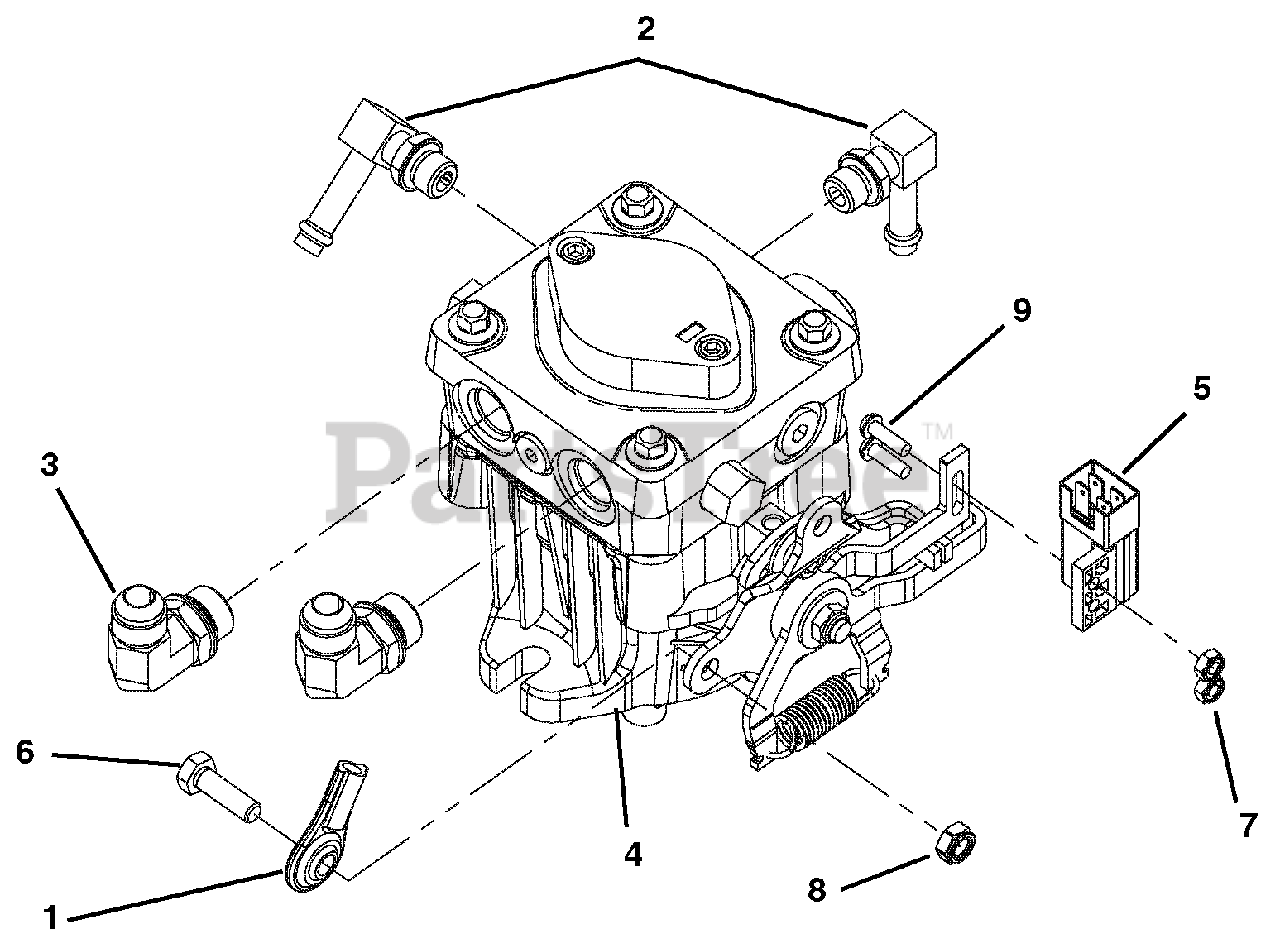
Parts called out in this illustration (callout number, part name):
1	Alignaball, 5/16 RH/Thread
2	Fitting, 90 9/16MOR x 3/8 Hose
3	Fitting
4	Pump, Hydraulic
5	Switch, Plunger Diametral Pitch -N.O. -N.C.
6	Bolt, Hex 5/16-18 x 1.00 Grade 5
7	Nut, Locking, Nylon 10-24 w/Insert
8	Nut, Locking, Nylon .312-18
9	Screw, Machine 10-24 x .62 P/HD
NS	Pump Seal Kit
